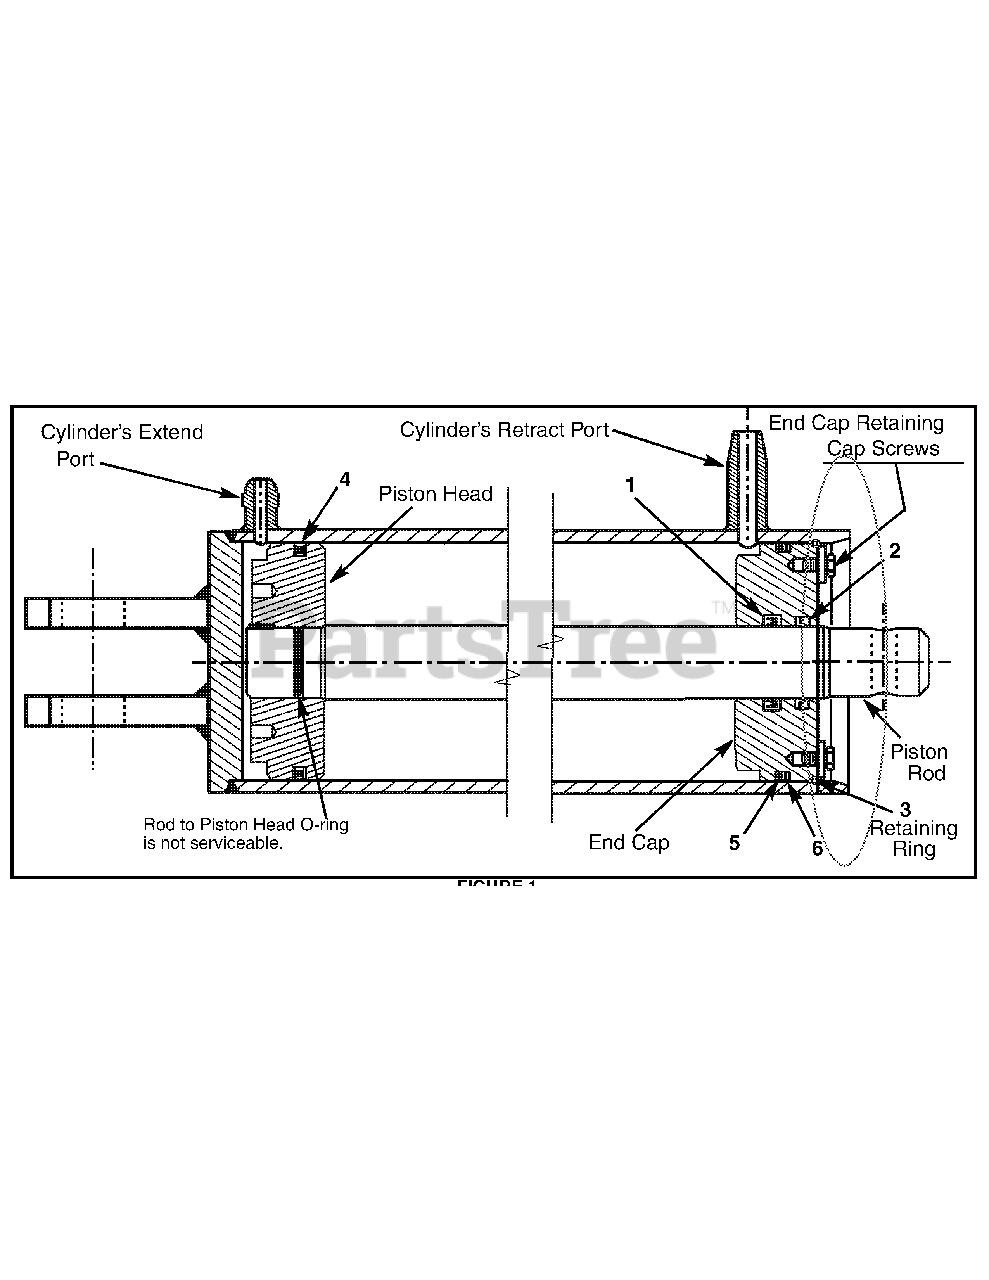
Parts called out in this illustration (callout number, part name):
1	Zurcon U-Cup RU3 (Blue)
2	Scraper DA17 (Black)
3	Retaining-Ring (Metal)
4	Zurcon Wynseal (Blue)
5	O-Ring (Black)
6	Back-up Ring (White)
7	INSTRUCTION SHEET
